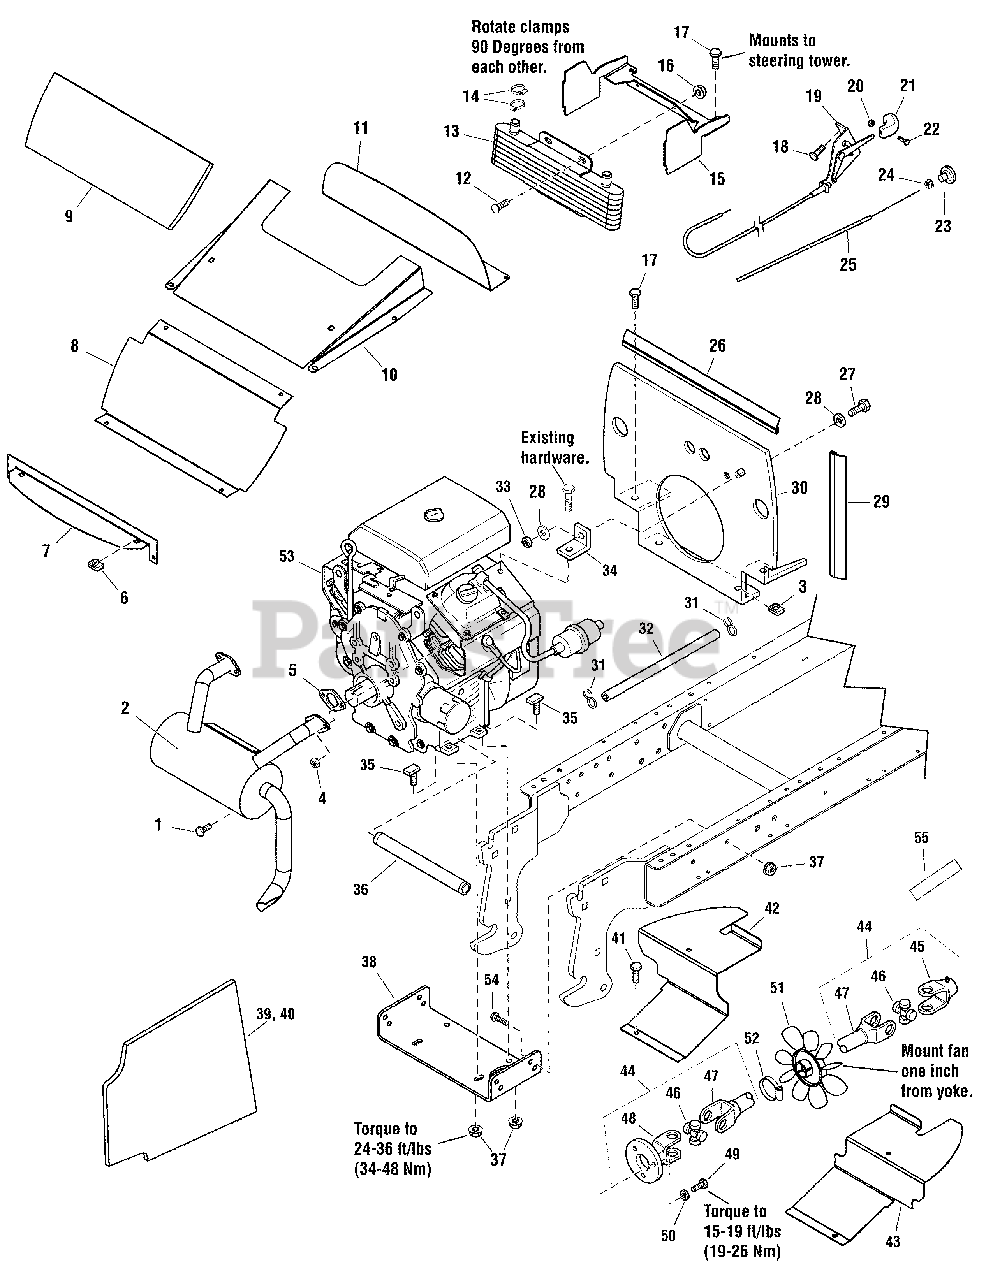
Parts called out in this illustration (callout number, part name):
1	SCREW, Hex Whiz Lock Flange, 3/8-16 X 3/4
2	MUFFLER, Kohler Gas
3	NUT, Lug, 5/16-18
4	NUT, Muffler
5	GASKET, Muffler
6	NUT, Retainer 1/4-20
8	PLATE, Hood 20GA
9	INSULATION, Foam 6 1/2 x 18 1/4
10	SHIELD, Hood 20GA
11	SHIELD, Rear Hood 18GA
12	CARRIAGE BOLT, 1/4-20 x 3/4 G5
13	COOLER ASSEMBLY, Oil
14	CLAMP, Hose
15	BRACKET, Cooler 12GA
16	NUT, Hex KEPS, 1/4-20
17	SCREW, Hex Washer Head Taptite 5/16-18 x 3/4
18	SCREW, Hex Washer Head
19	CONTROL, Throttle
20	NUT, Hex Lock, 10-24
22	SCREW, Pan Head Phillips #10-24 x 1
23	KNOB, Intermediate Thread #10-24 1.43LG
24	NUT, Hex KEPS #10-24
25	CONTROL, Choke
26	EDGING, 18.0 LG
27	CAPSCREW, Hex Head, 1/4-20 x 3/4 G5
28	WASHER, 3/4
29	EDGING, 12-5 LG
30	SHIELD, Heat 16 GA
31	CLAMP, Hose
32	HOSE, Fuel
33	NUT, Hex Lock, ESNA 1/4-20NC-3B
34	CLIP, "L" 1 3/8 + 7/8LEG 3/4
35	STUD, 3/8-16 x 1 9/10
36	HOSE, Oil Drain
37	NUT, Hex KEPS 3/8-16
38	BASE, Engine
39	INSULATION, Foam
40	INSULATION, Foam
41	SCREW, Hex Whiz Lock Flange 5/16-18 x 3/4
42	SHIELD, R.H. 16GA
43	SHIELD, L.H. 16GA
44	SHAFT ASSEMBLY, Drive
45	YOKE & FLANGE, Drive Shaft
46	CROSS & BEARING KIT, Includes Grease Fitting
47	YOKE & TUBE ASSEMBLY
48	YOKE, Drive Shaft
49	CAPSCREW, Hex Head
50	LOCKWASHER, Spring
52	CLAMP, Worm Hose
54	SCREW, Hex, Whiz Lock Flange 3/8-16 x 1
55	TAPE, Double Sided Foam 7/8 x 4-3/4
